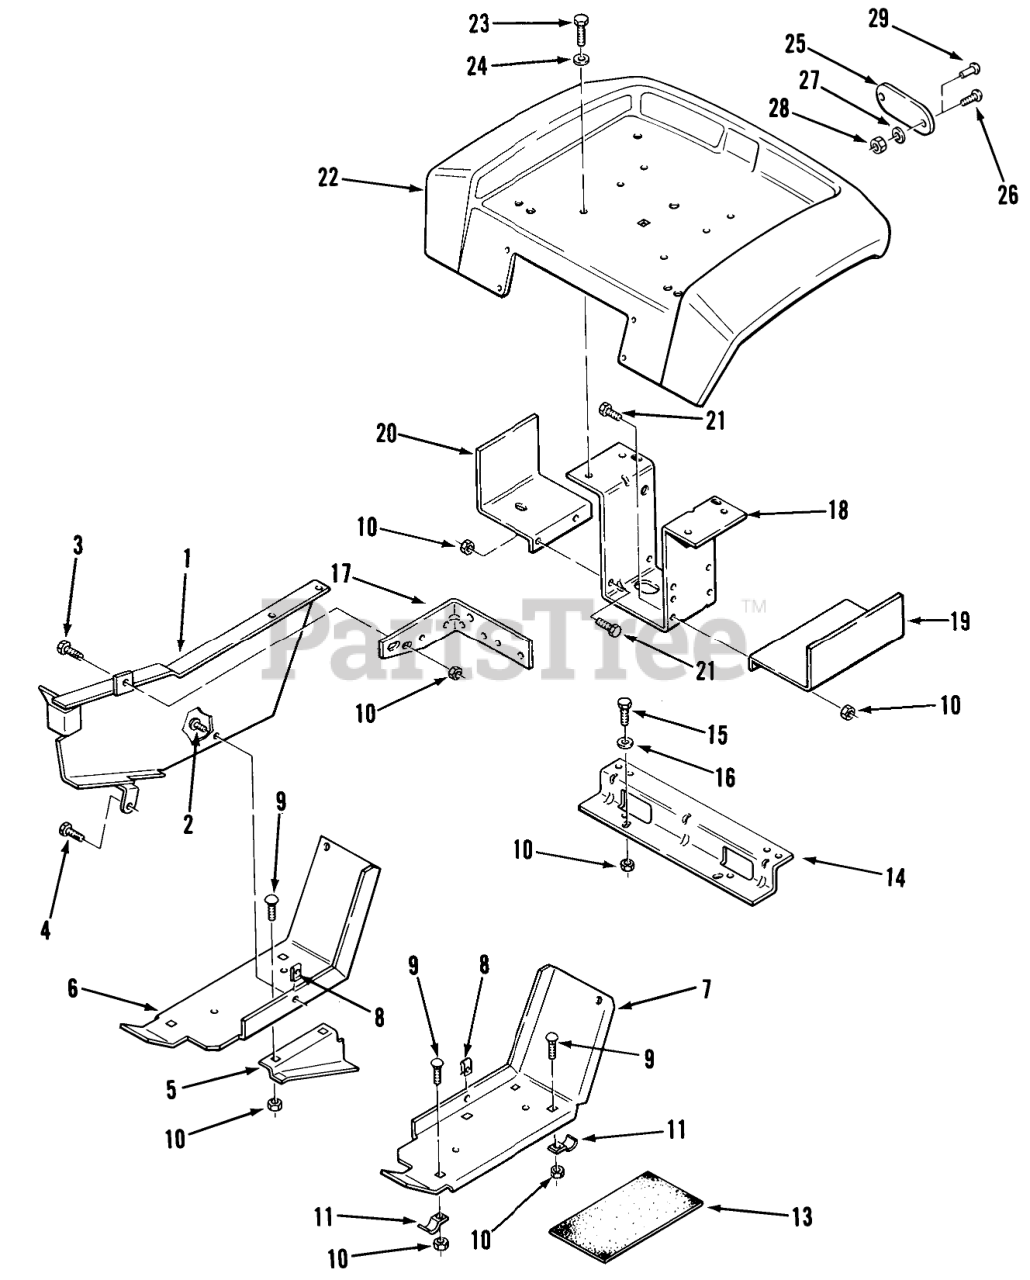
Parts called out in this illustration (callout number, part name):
1	BELT GUARD ASM
1	Belt Guard GT-1100 Only
2	Screw
2	ANGL-BLT GURDB
3	Bolt
4	SCREW
5	GUID-LOWER BLTR
6	Foot Rest RH
7	Foot Rest LH
9	CARRIAGE BOLT -4
10	Nut
11	BRACKET
13	PAD-FOOTREST
14	BRACKET-FENDER B
15	Bolt
16	WASHER 5/16 SAE
17	BRACKET-BELTB
18	Bracket-Fender Support
19	Fuel Tank Support LH
20	Support-FueITank RH
21	Bolt
22	Fender
23	Bolt
24	WASHER 5/16 SAE
25	Reflector
26	Screw
27	Lockwasher
28	Nut
29	Poprivet
